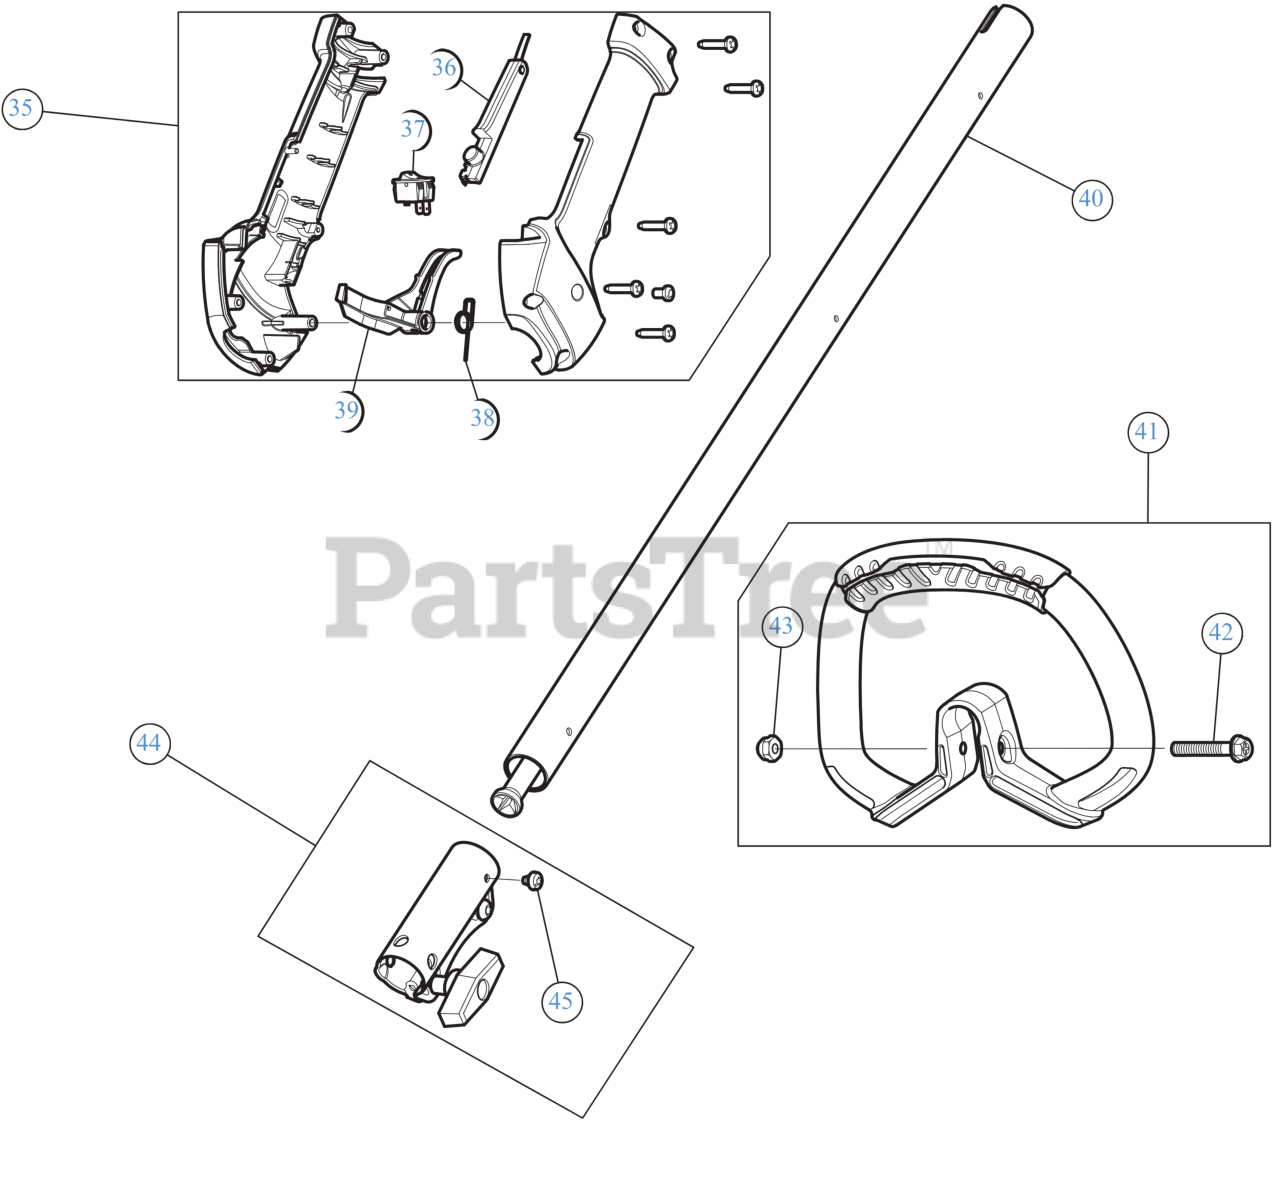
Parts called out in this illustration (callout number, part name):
35	THROTTLE GRIP ASSEMBLY
36	LEVER LOCK OUT
37	SW, MOMENTARY ON/O
38	TRIGGER SPRING
39	THROTTLE TRIGGER
40	UPPER SHAFT HOUSING
41	HANDLE DLX
42	BOLT 1/4-20X1 1/2
43	NYLON LOCK NUT
44	COUPLER ASSEMBLY
45	SCREW, 10-32X.250 TA
